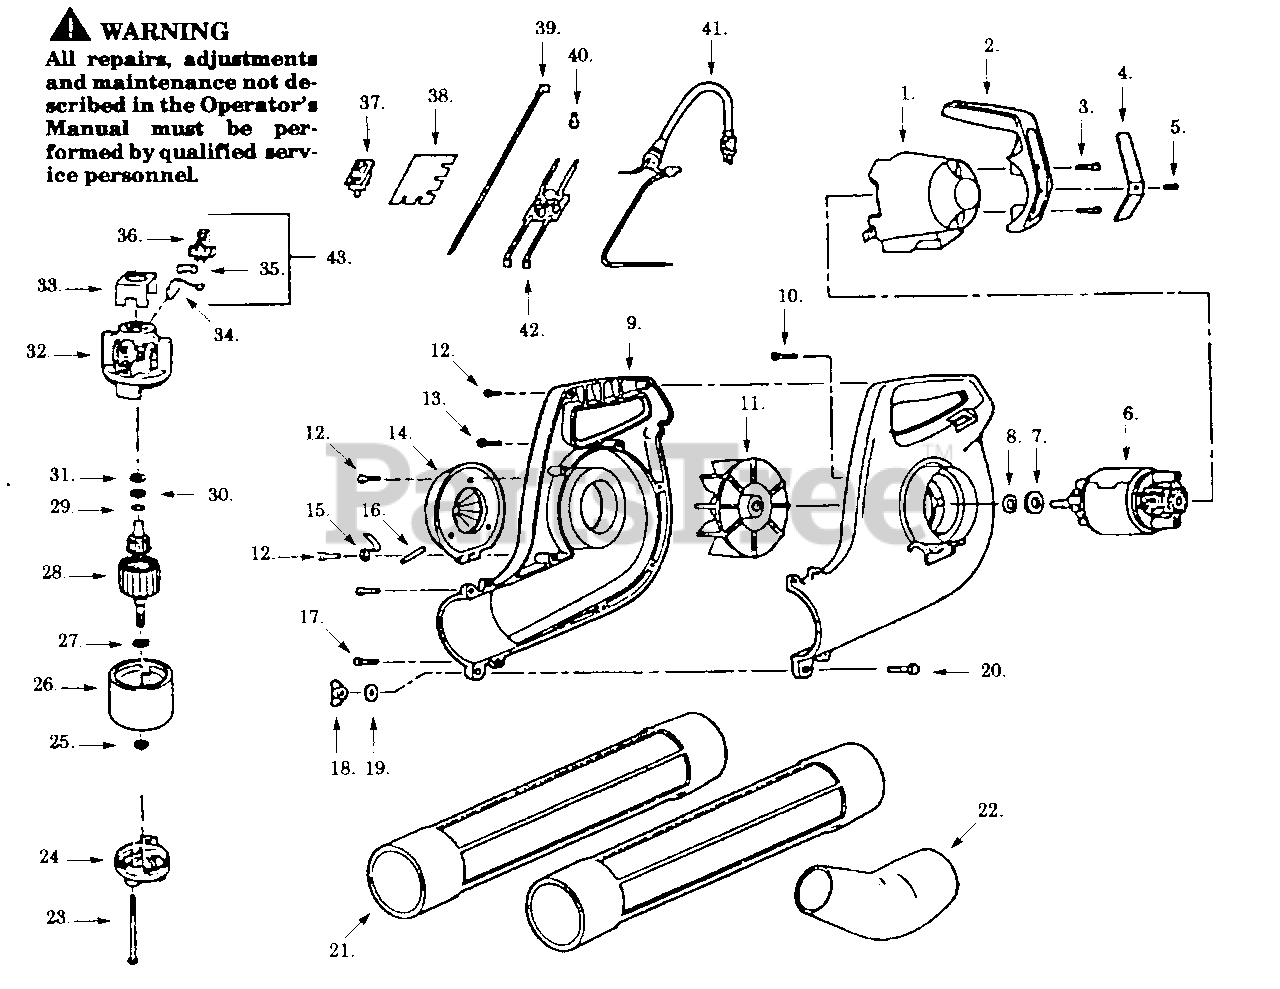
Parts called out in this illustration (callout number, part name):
1	Motor Cover
8	Retaining Ring
9	R.H./L.H. Housing
11	Impeller Ass'y.
14	Inlet Cover
16	Hinge Pin
18	Wing Nut
21	Outlet Tube
22	Curved Nozzle
24	Endbell Ass'y. (Drive)
26	Field Ass'y.
27	Retaining Ring
28	Armature Ass'y.
29	Retaining Ring
32	Endbell Ass'y. (Brush)
33	Insulator
35	Brush Spring
36	Brush Holder
37	On-Off Switch
38	Mounting Board
39	Leadwire Ass'y.
40	Connector
41	Power Cord Ass'y.
42	P.C. Board Ass'y.
43	Brush Kit (Incl. 34,35,36)
